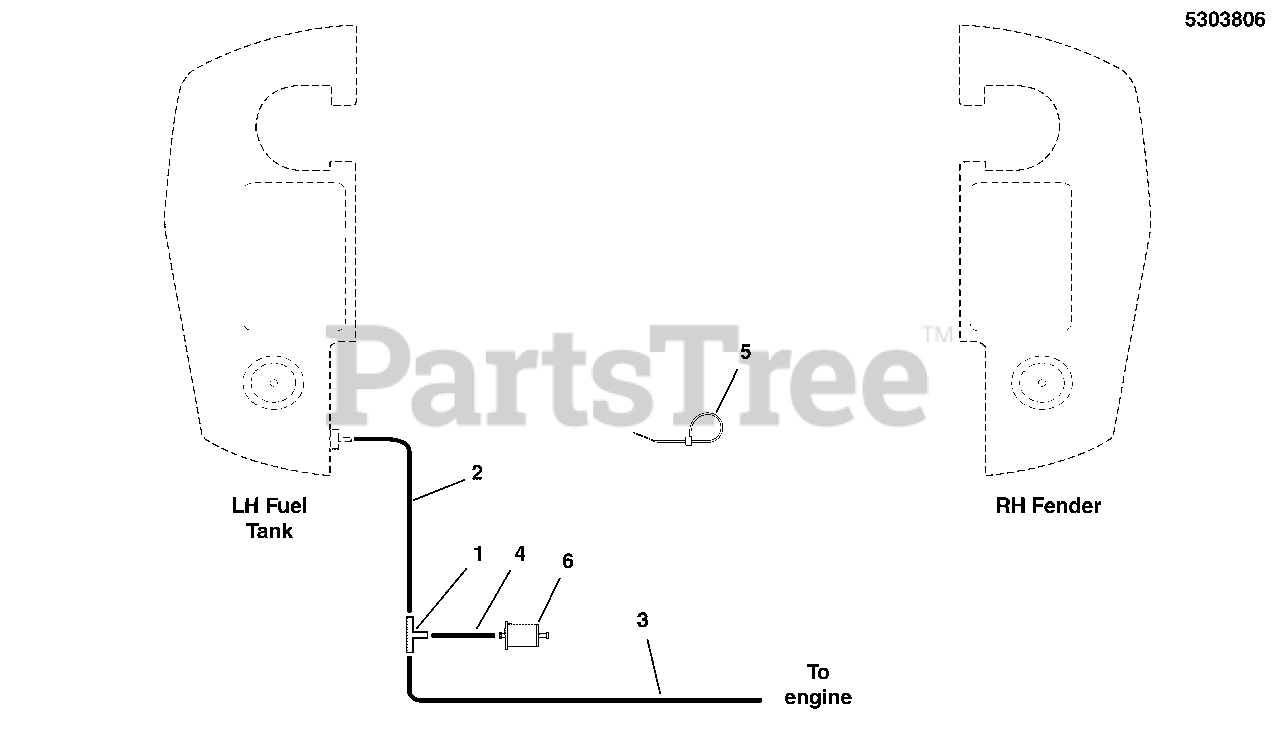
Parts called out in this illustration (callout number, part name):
1	FITTING, 3/16" TEE, BARB TYPE, HDPE
2	HOSE, VAPOR, 5MM ID, 27.00 LG
3	HOSE, VAPOR, 5MM ID, 12.00 LG
4	HOSE, VAPOR, 5MM ID, 2.00 LG
5	TIE,SELF-LOCKING, 6"
6	FILTER, Fuel
